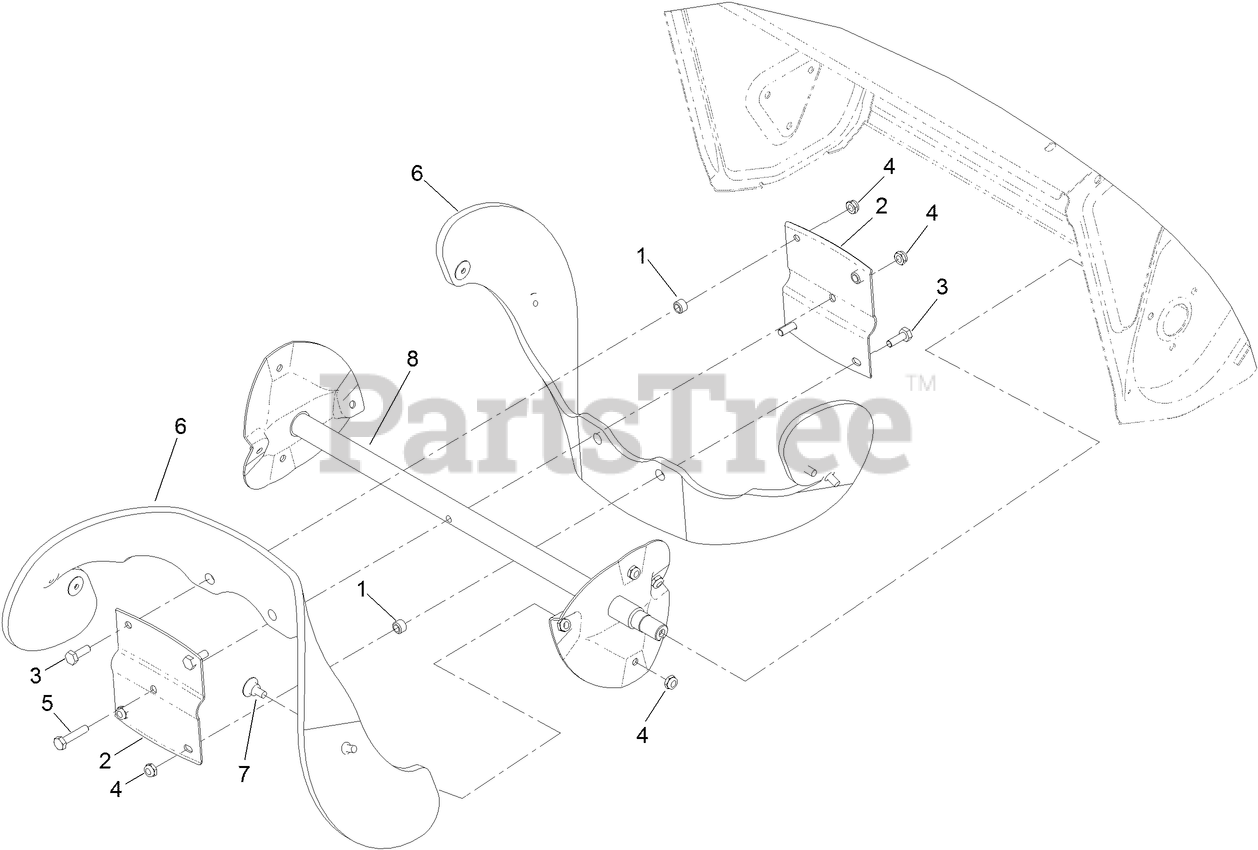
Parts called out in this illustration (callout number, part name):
1	SPACER-BLADE, ROTOR
2	HALF-ROTOR
3	SCREW-HH
4	NUT-LOCK, NI
5	SCREW-HH
6	BLADE-ROTOR
7	SCREW
